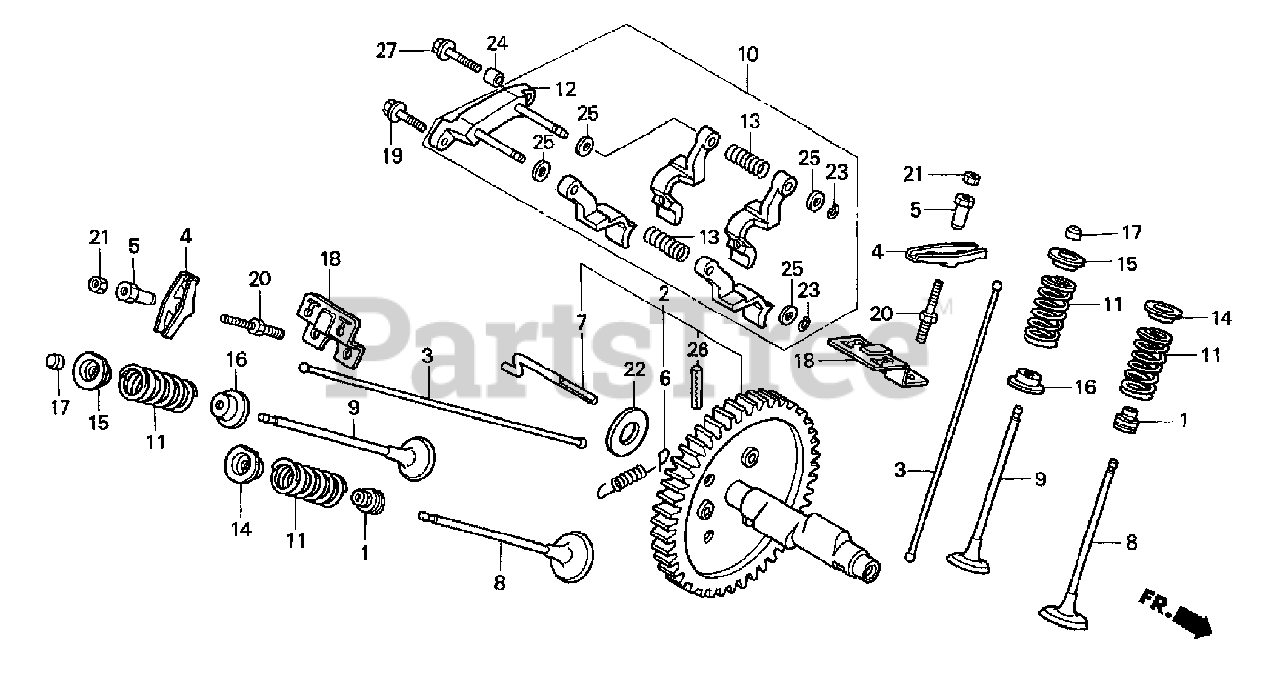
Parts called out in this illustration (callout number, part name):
1	Seal, Valve Stem
2	Camshaft Assembly
4	Arm, Valve Rocker
5	Pivot, Rocker Arm
6	Spring, Weight Return
7	Pin, Decompression
10	Lifter Ass’y., Valve
11	Spring, Valve
12	Shaft, Valve Lifter
13	Spring, Valve Lifter
14	Retainer, In. Valve Spring
15	Retainer, Ex. Valve Spring
16	Seat, Valve Spring
17	Rotator, Valve
18	Plate, Push Rod Guide
19	Bolt, Flange (5x16)
20	Bolt, Pivot (8mm)
21	Nut, Pivot Adj
22	Washer, Thrust (17.2mm)
23	Clip, Governor Holder
24	Pin A, Dowel (8x12)
25	Washer, Plain (6mm)
26	Pin, Spring (6x28)
27	Bolt, Flange (6x25)
